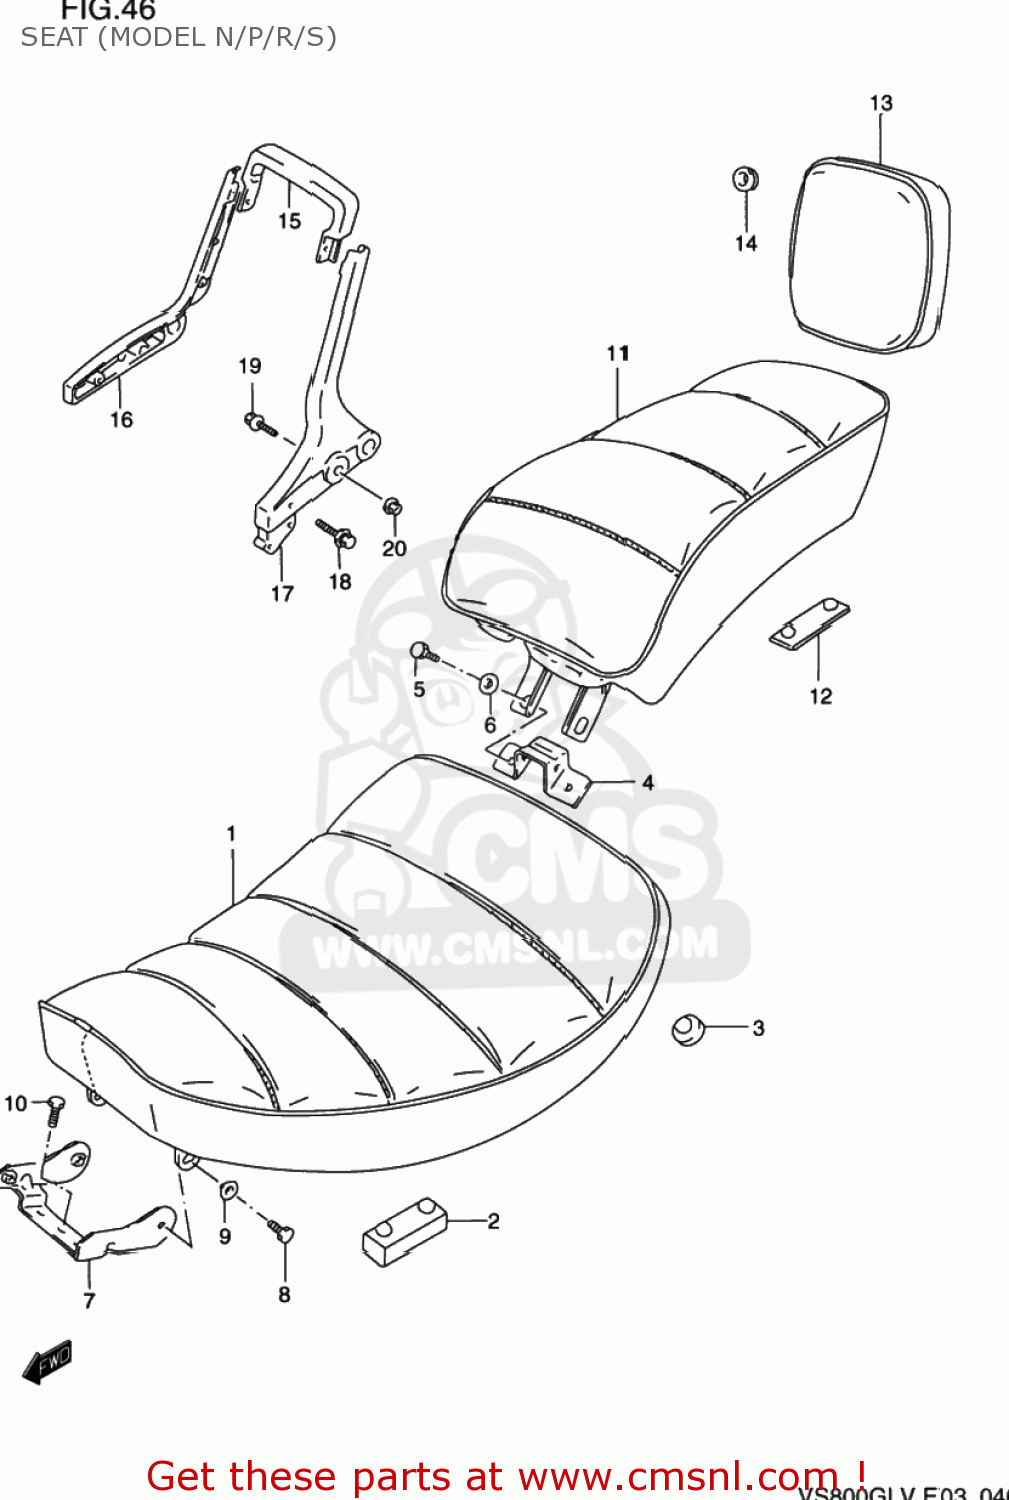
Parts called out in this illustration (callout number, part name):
1	SEAT SET
2	CUSHION,SEAT
3	CUSHION
4	PLATE,FR SEAT HOOK & RR
5	BOLT
6	WASHER
7	BRACKET,SEAT,FRONT
8	BOLT
9	WASHER
10	BOLT
11	SEAT ASSEMBLY,PILLION
12	CUSHION
13	PAD ASSY,SEAT
14	CUSHION
15	HANDLE,PILLION RIDER UPR
16	HANDLE,PILLION RIDER,R
17	HANDLE,PILLION RIDER
18	BOLT
19	BOLT
20	NUT
